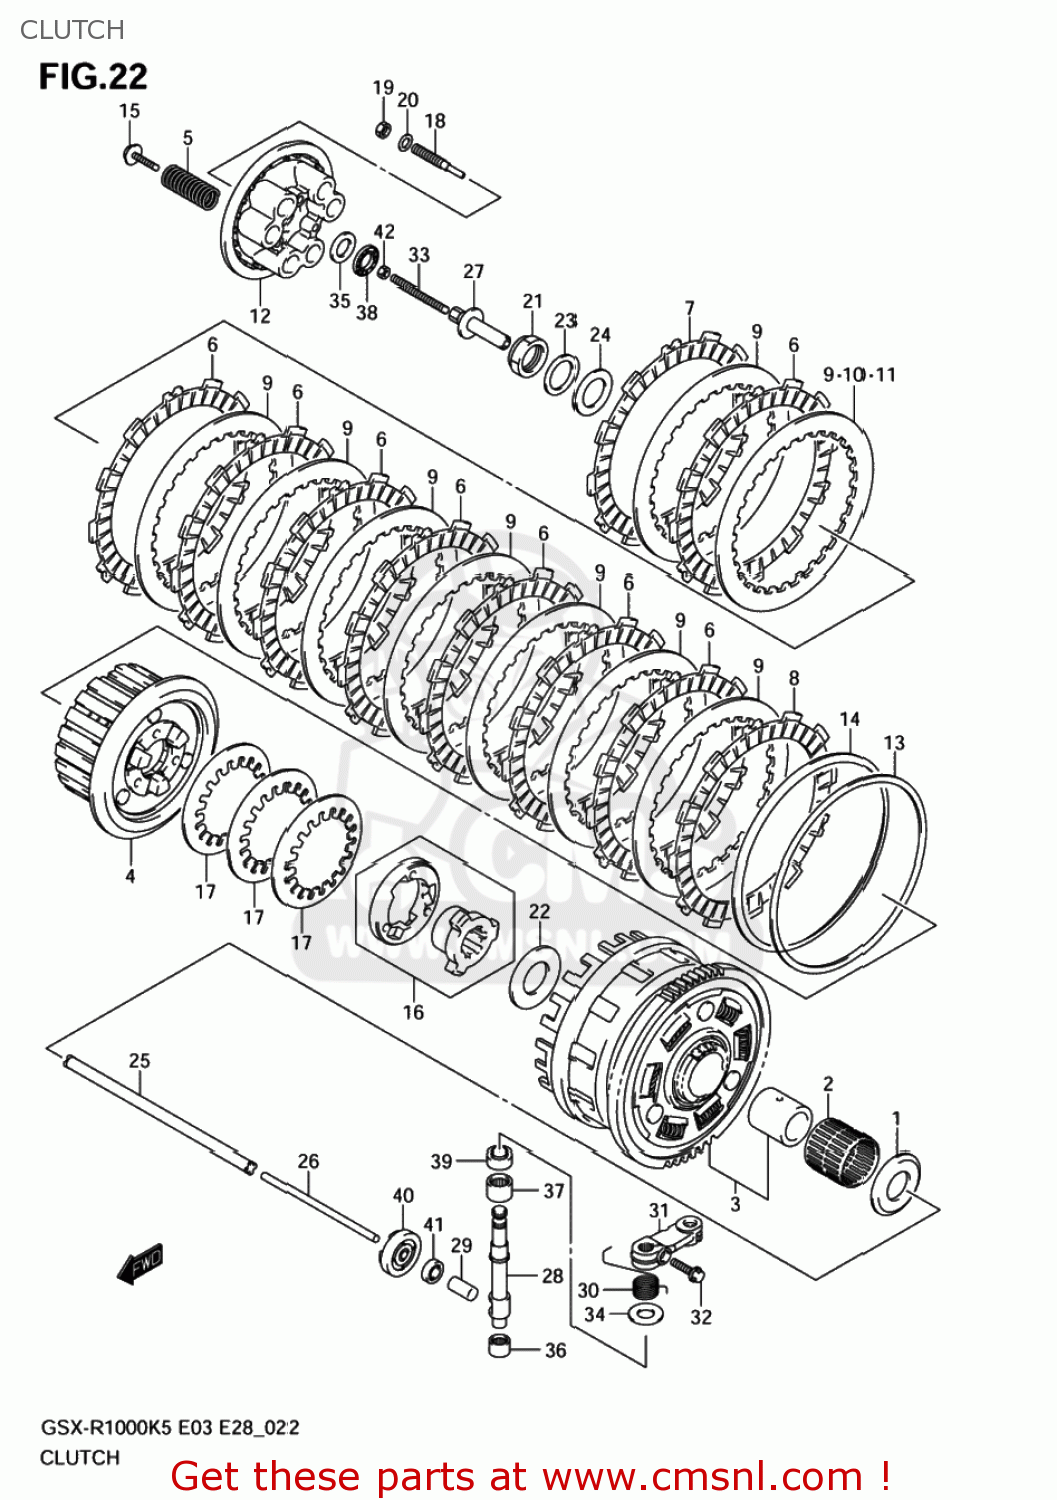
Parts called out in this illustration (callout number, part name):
1	WASHER(25X54X2.4)
2	BEARING(35X40X35.8)
3	GEAR ASSY,PRI DRIVEN
4	HUB,CLUTCH SLEEVE
5	SPRING,CLUTCH
6	PLATE,CLUTCH DRIVE (NAS)
7	PLATE,CLUTCH DRIVE (NAS)
8	PLATE,CLUTCH DRIVE NO.3 (NAS)
9	PLATE,CLUTCH DRIVEN(T:2.3) (NAS)
10	PLATE,CLUTCH DRIVEN (NAS)
11	PLATE,CLUTCH DRIVEN (NAS)
12	DISC,CLUTCH PRESSURE
13	SEAT,WAVE WASHER
14	WASHER,CLUTCH PLATE WAVE
15	BOLT,CLUTCH SPRING
16	CAM SET,CLUTCH
17	WASHER,CAM REACTION WAVE
18	LIFTER,CLUTCH PRESSURE DISC
19	NUT,CL PRESS DISC LIFTER LOCK
20	SHIM(8.8X14X1)
21	NUT
22	WASHER(25X50X2.5)
23	WASHER(25X41X2.5)
24	WASHER
25	ROD,CLUTCH PUSH,R
26	ROD,CLUTCH PUSH,L
27	PIECE,CLUTCH PUSH
28	CAMSHAFT,CLUTCH RELEASE
29	CAP,CLUTCH PUSH ROD
30	SPRING,CLUTCH RELEASE RETURN
31	ARM,CLUTCH RELEASE
32	BOLT(6X20)
33	SCREW(6X73)
34	WASHER(10.5X24X1)
35	WASHER(15.5X28X1)
36	BEARING(10X14X10)
37	BEARING(12X18X12)
38	BEARING(15X28X2)
39	SEAL,OIL(10X20X6)
40	SEAL,OIL(6X34X10)
41	SEAL,OIL(10X17X5)
42	NUT 6MM
